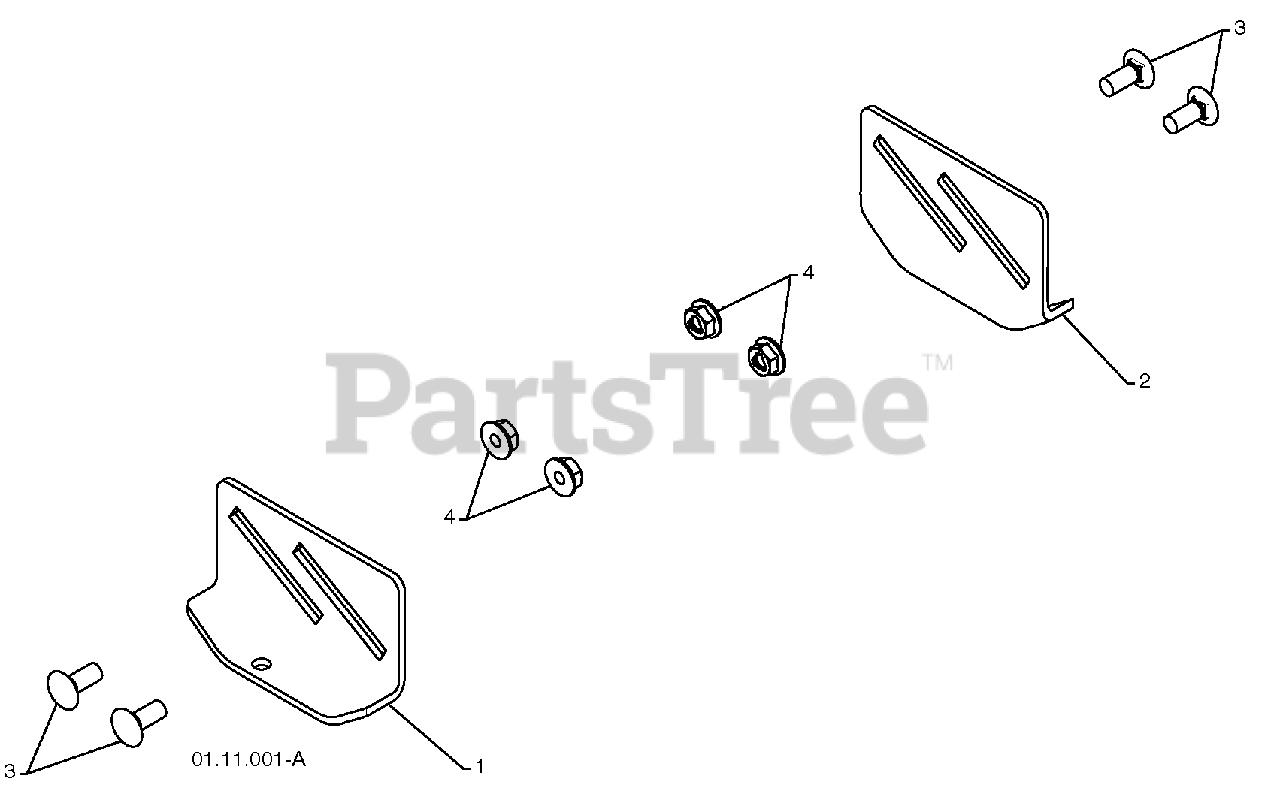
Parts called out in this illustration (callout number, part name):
1	SKID PLATE LH
2	SKID PLATE RH
3	CARRIAGE BOLT 5/16-18 X .75
4	NUT 5/16-18
